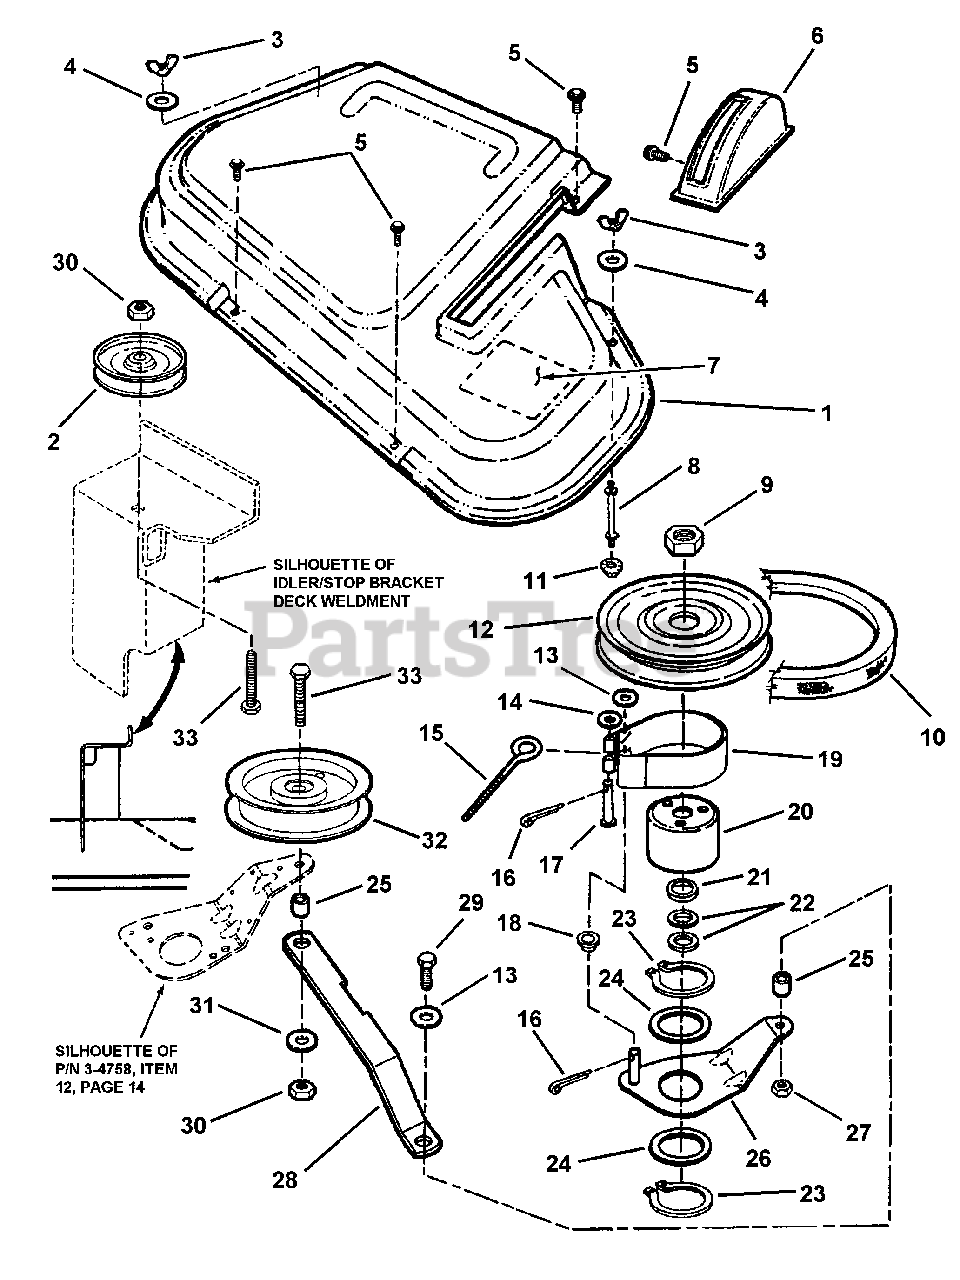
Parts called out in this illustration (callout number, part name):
1	COVER, Spindle 42"
2	PULLEY, Seam Welded Idler (.375" ID, 4" OD)
3	WINGNUT, 5/16-18
4	WASHER, 11/32" x 11/16" x 1/16" Flat
5	SCREW, 1/4-20 x 5/8" Hex Washer Head, Self-Tap
6	COVER, Lift Quadrant
7	DECAL, Brake Operation
8	STAND-OFF, 3-1/2"
9	NUT, 3/4-16 Hex Jam
10	BELT, (110.28", "5L" Section)
11	NUT, 3/8-16 Hex Flange Lock
12	PULLEY, 5" O.D.
13	WASHER, 3/8" Flat
14	WASHER, 1/4 Flat
15	EYE-BOLT, 5/16-18 x 3"
16	COTTER-PIN, 3/32 x 3/4"
17	PIN, 1/4 x 1-5/8" Clevis
18	SPACER
19	ASSEMBLY, Brake Band
20	DRUM, Brake 3" OD
21	SPACER, 3/4" I.D.
22	WASHER, 3/4" Flat
23	RING, 2" External Retaining
24	WASHER, 2" I.D., Nylon
25	SPACER
26	WELDMENT, Brake Arm
27	NUT, 3/8-24 Hex Center Lock
29	SCREW, 3/8-24 x 1" Hex Head Cap Grade 5
30	NUT, 3/8-16 Hex Nyloc
31	WASHER, 3/8" Flat
32	PULLEY, 4-1/8" Flat Idler, .375" ID
33	SCREW, 3/8-16 x 1-1/2" Hex Head Cap Grade 5
